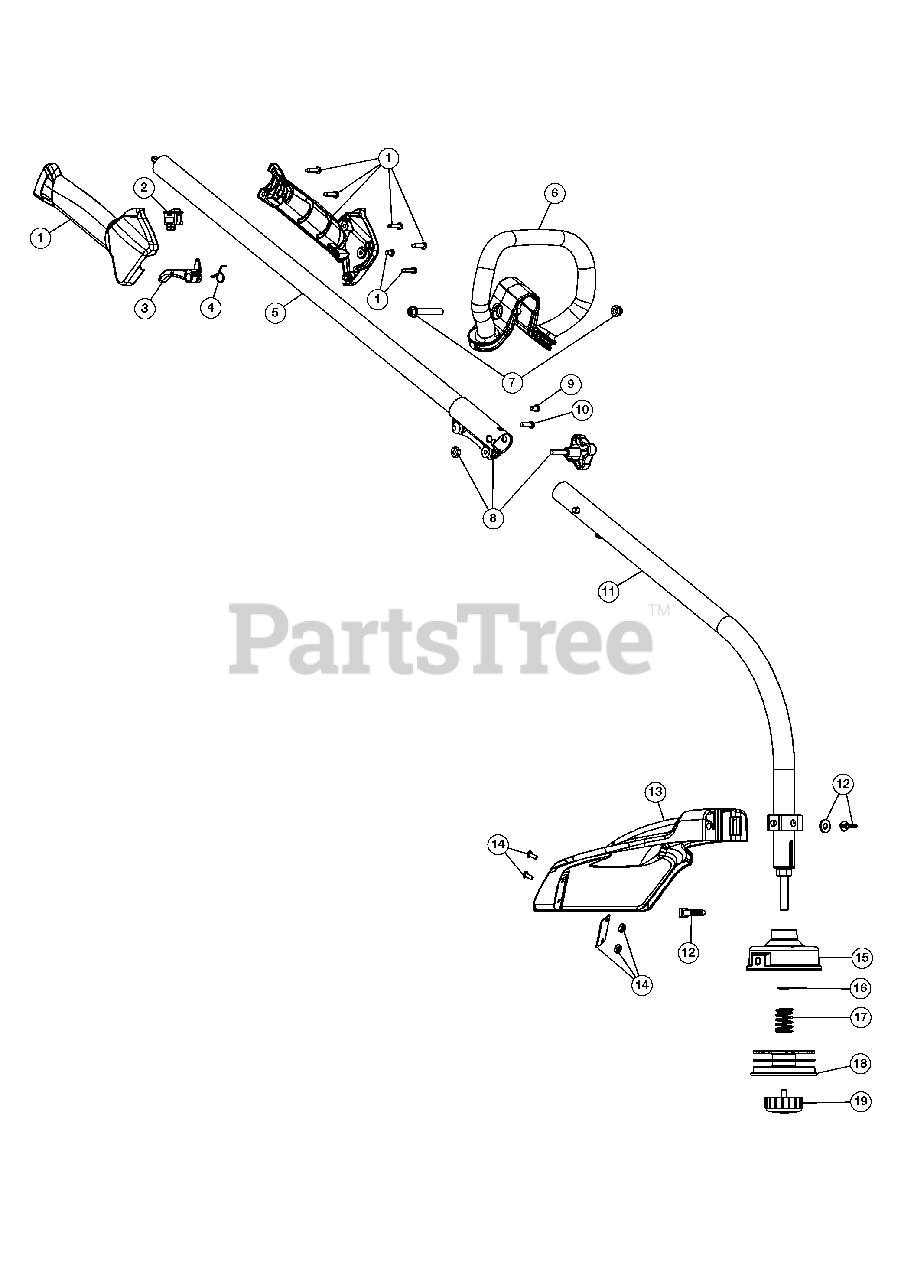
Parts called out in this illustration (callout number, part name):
1	Throttle Housing Assembly (Incl. 2-4)
3	Throttle Trigger
4	Throttle Trigger Spring
5	Upper Shaft Housing Assembly
6	D-Handle (Incl. 7)
7	D-Handle Bolt
8	Split Boom Coupler (Incl. 9-10)
9	Anti-Rotation Screw
11	Lower Shaft Housing Assembly
12	Shield Mounting Hardware
13	Shield Assembly (Incl. 14)
14	Blade Assembly
15	Outer Spool Assembly (Incl. 16)
16	Retainer
18	Inner Reel
19	Bump Head Knob Assembly
